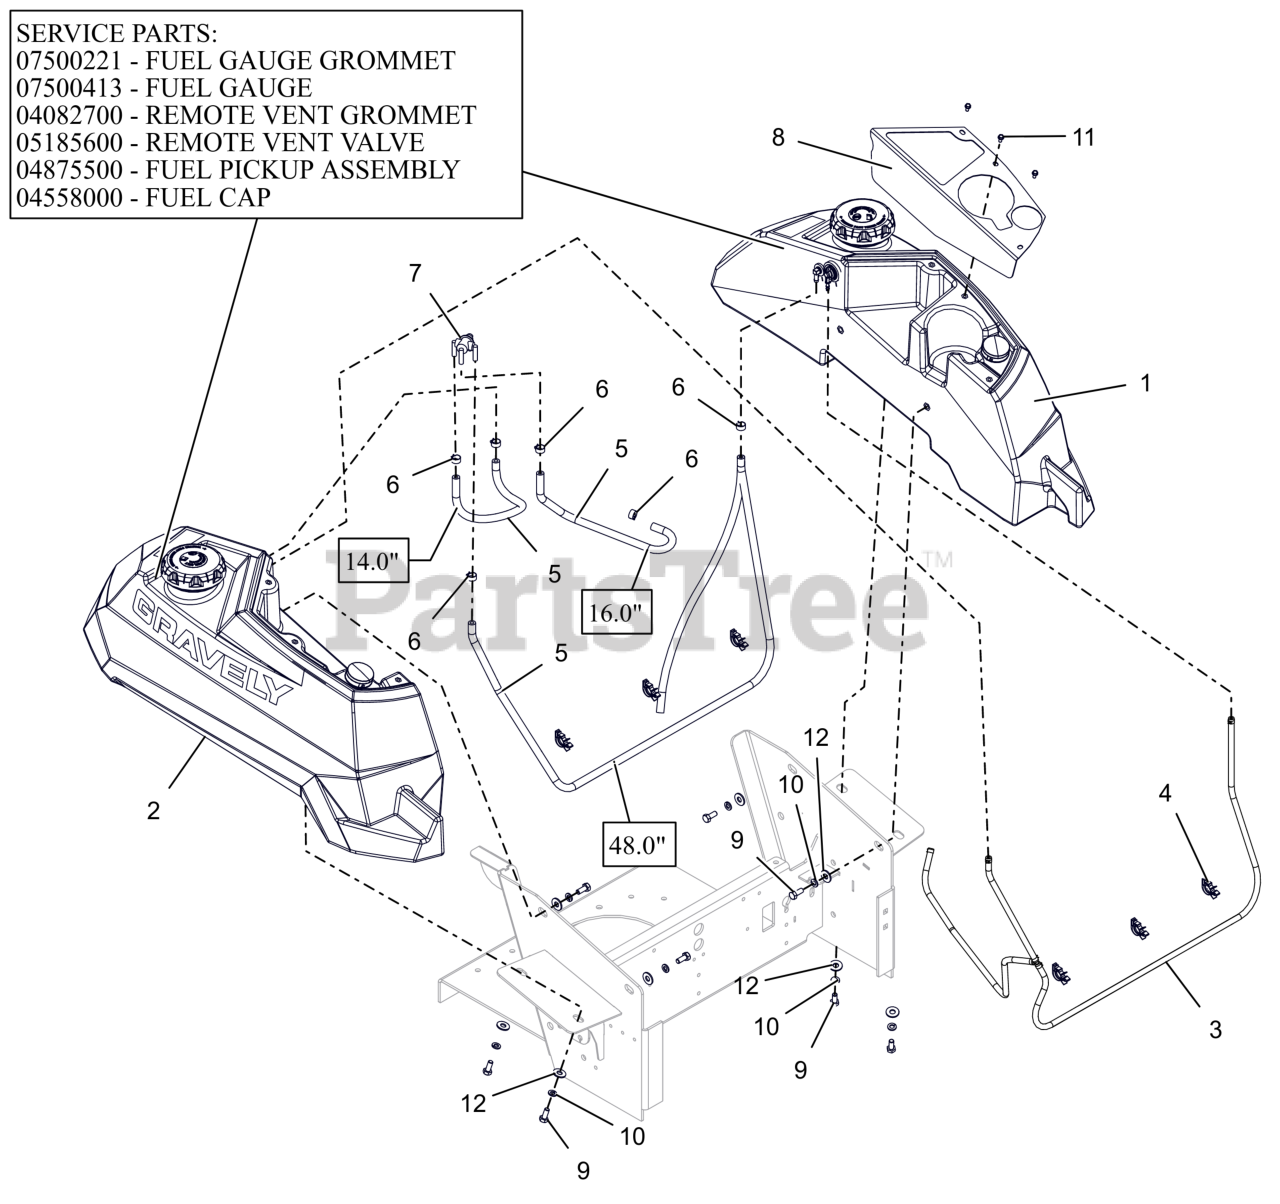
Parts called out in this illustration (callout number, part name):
1	ASM, LH - PT100 FUEL TANK
1	GROMMET, FUEL GAUGE
1	GAUGE, REMOTE SEALED FUEL
1	GROMMET, REMOTE VENT NITRILE
1	VALVE, COMBINATION VENT 3/16
1	ASSM,LRG TANK FUEL PICKUP LINE
1	CAP, FUEL VENTIN AUTOLOCK
2	ASM, RH - PT100 FUEL TANK
2	GROMMET, FUEL GAUGE
2	GAUGE, REMOTE SEALED FUEL
2	GROMMET, REMOTE VENT NITRILE
2	VALVE, COMBINATION VENT 3/16
2	ASSM,LRG TANK FUEL PICKUP LINE
2	CAP, FUEL VENTIN AUTOLOCK
3	ASM, VAPOR LINE
4	WIRE CLIP
5	HOSE, .25 LOW-PERM BULK GAS
6	CLAMP, FUEL LINE
7	VALVE, FUEL
8	PT100 CUPHOLDER PANEL - RED
9	BLT,HEX .31-18X.75 G5 ZCC
10	WSHR,LK-REG .312X.078 ZCC
11	SCR-MCH 10-24X.38 HWHSTAINLESS
12	WSHR,FLT .375X.875X.083 ZCC
